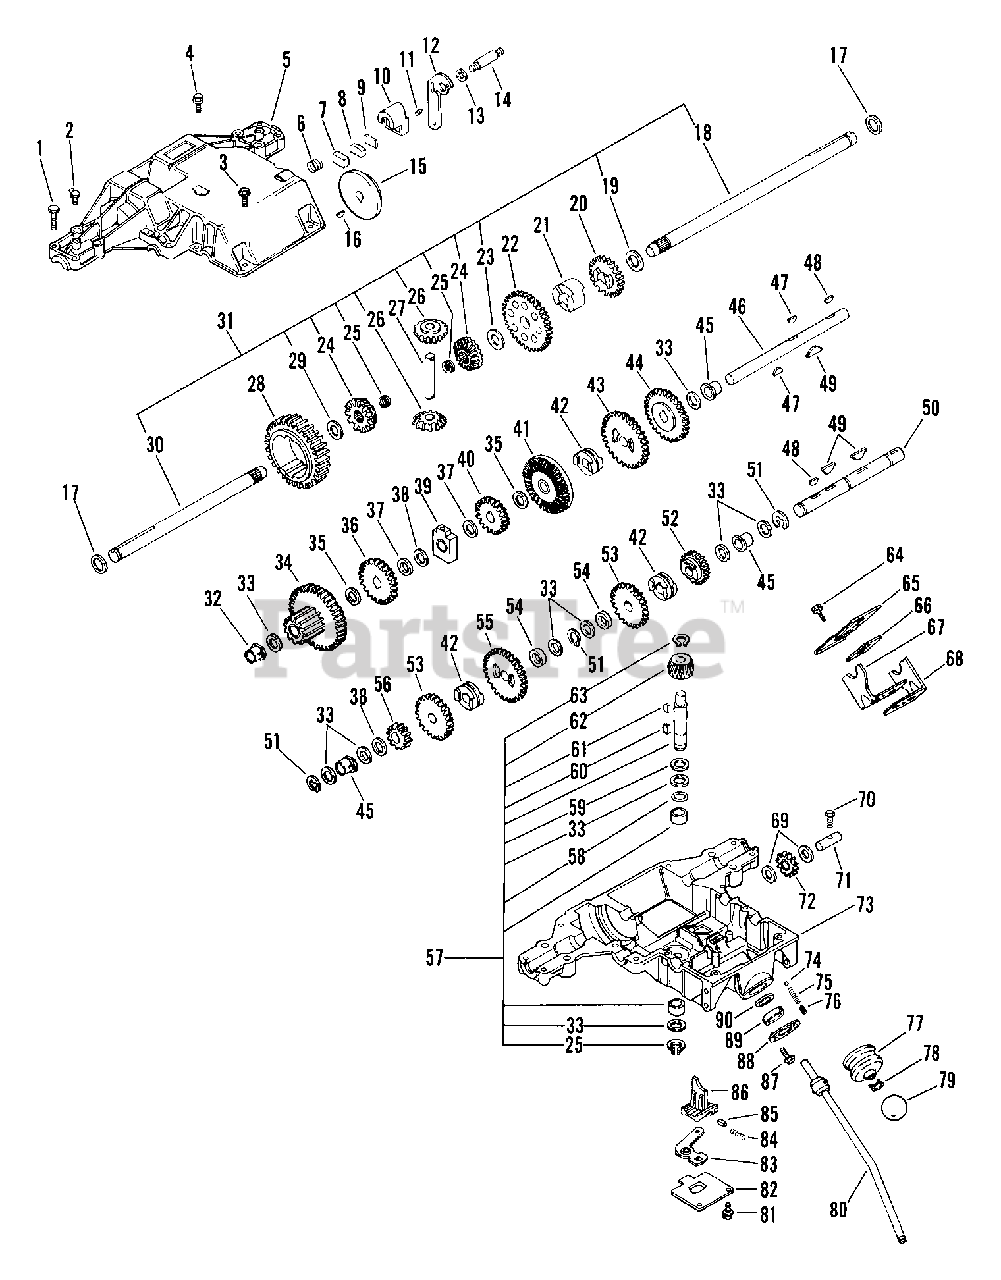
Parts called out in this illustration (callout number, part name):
1	BLT-HEX .25-20X1.25 PL GR5
2	ZERK FITTING
3	SCR-TAP .250-20X.860 HH
4	SCR-MCH 12-24X.62 HEXWH
5	LOWER HOUSING ASSEMBLY
6	SG-COMP J.B. FOOTE
7	FRICTION PAD
8	BRAKE JAW FRICTION PUCK
9	SPACER - FLAT .045 THICK
10	BRAKE JAW ASSY
11	SCR-SET 8-32 FOOTE 1606
12	ACTUATING LEVER ASSY
13	WSHR-FL-STL .505X.750X.006
14	SHOULDER BOLT
15	BRAKE DISC
16	KEY-WDRF .188X.625X.25 SAE 61
17	SEAL J.B.FOOTE #5130
18	R H AXLE
18	AXLE, RH
19	WSHR-FL-STL .760X1.250X.060 PL
20	SPUR GEAR 22T
21	GEAR LOCK
22	SPUR GEAR 35T
23	WSHR-HDND-THRST .758X1.23X.031
24	SPLINED MITER GEAR 15T
24	GEAR,MITER,15T,SPLINED
25	RG-RTNG-EXT .625X.035
25	RING-RETAINING
26	MITER GEAR 15T
26	GEAR,MITER,15T
27	CROSS SHAFT ASSEMBLY
27	SHAFT, CROSS
28	GEAR & SHAFT ASSEMBLY
28	GEAR, SPUR, 32T.
29	SHIM PACKAGE
30	L H AXLE
30	AXLE, LH
31	DIFFERENTIAL ASSEMBLY
32	FLANGE BEARING
33	SHIM PACKAGE
34	GEAR ASSEMBLY
35	WASHER
36	SPUR GEAR 25T
38	SPACER .630X1.000X.110
39	SHAFT SUPPORT ASSY
40	SPUR GEAR 20T
41	BEVEL GEAR ASSY
42	CLUTCH COLLAR
43	SPUR GEAR 33T
44	SPUR GEAR 30T
45	FLANGE BEARING
46	DRIVE SHAFT
47	KEY-WDRF FOOTE #3311
48	KEY-WDRF .125X.500X.203 SAE 3
49	KEY-FTHR FOOTE #3068
50	INTERMEDIATE SHAFT
51	RG-RTNG-EXT .625X.042
52	SPUR GEAR 20T
53	SPUR GEAR 25T
54	SPACER .633X1.00X.260
55	SPUR GEAR 30T
56	SPUR GEAR 13T
57	INPUT SHAFT ASSY KIT
58	O-RING .612X.805X.102
60	KEY-WDRF .188X.75X.313 SAE 9
61	KEY-WDRF .125X.500X.203 SAE 3
63	RG-RTNG-EXT .500X.035
64	BLT-HEX .25-28X.75 PL GR5
65	LOCK-OUT PLATE
66	FORK PLATE SUPPORT
67	SHIFTER FORK
68	SHIFTER FORK
69	WSHR-FL-STL .505X1.000X.020
70	SCR-MCH 10-24X1.00 HEX PL
71	IDLER SHAFT
72	IDLER GEAR ASSY
73	UPPER HOUSING
74	DETENT BALL
75	SG-COMP ??X??X?? FOOTE
76	SCR-SET .25-20X.38 SKHCUP OH
77	BOOT-SWITCH
78	CLAMP-HOSE WIR.490/.510X.092#8
79	SHIFT BALL
80	SHIFT LEVER ASSY
81	SCR-MCH 8-32X.50 SLTR PL
82	HI-LO COVER PLATE
83	HI-LO SHIFT LEVER
84	SG-COMP .035X.186X.702
85	DETENT PIN
86	HI-LO SHIFTER FORK
87	SCR-TAP 10-24X.484 HWH TR
88	NYLON COVER
89	NYLON INSERT
90	WAVE WASHER .760X1.062X.105FH
